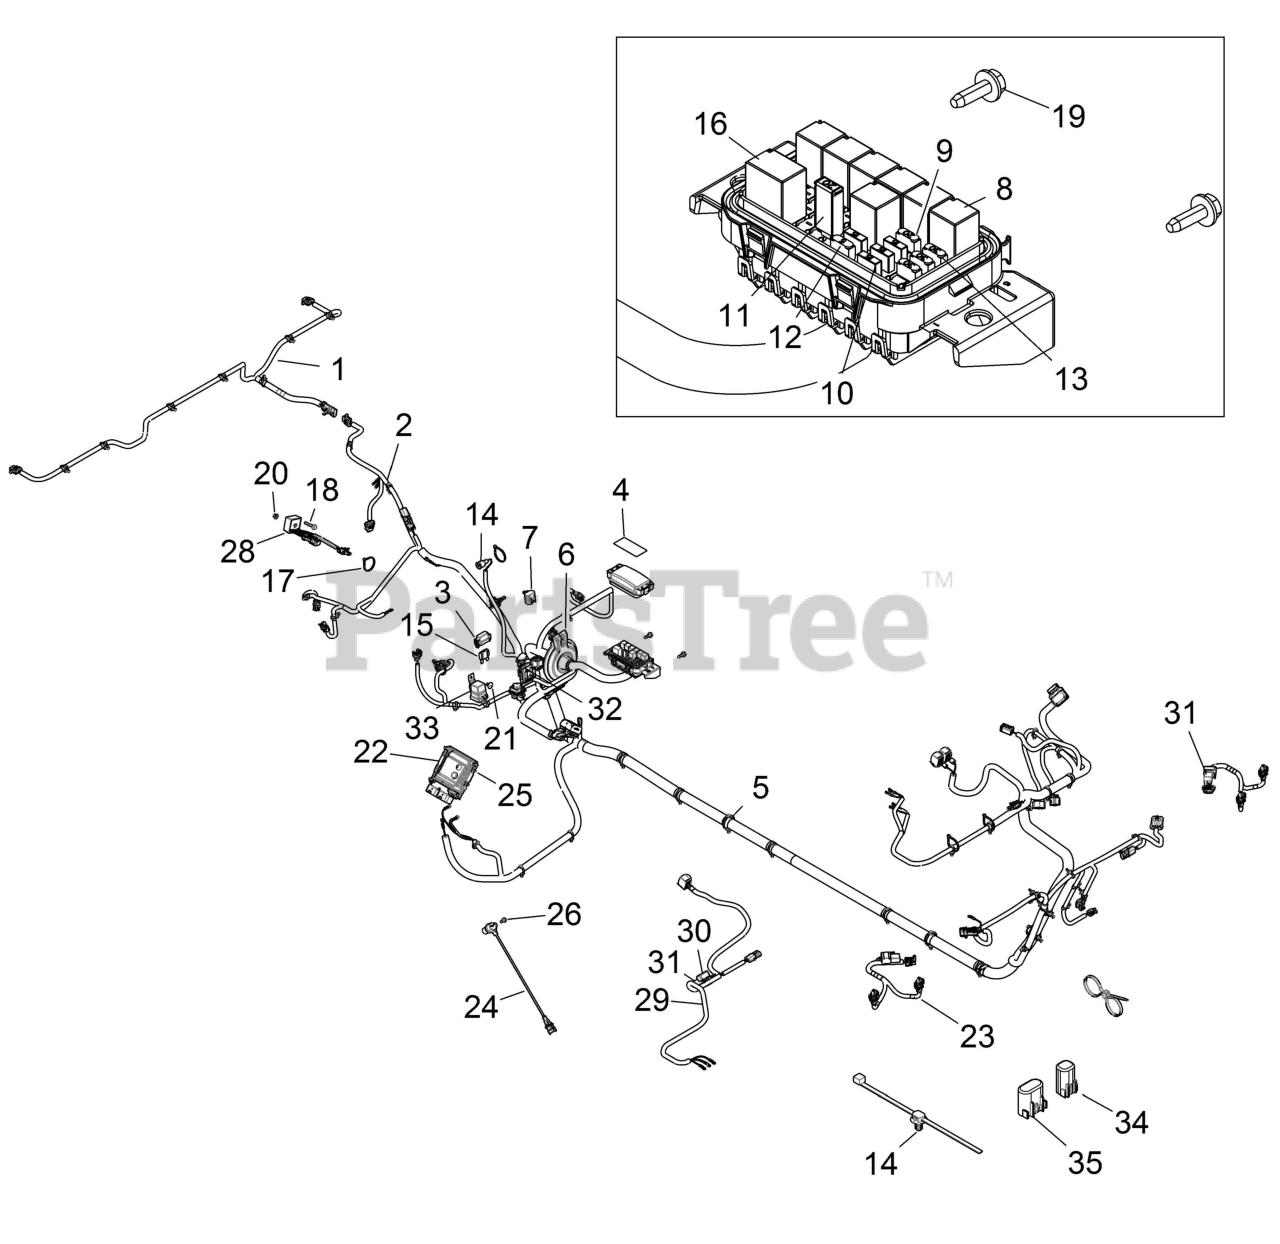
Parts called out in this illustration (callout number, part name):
1	HARNESS-BOX-ARIENS SPLY
2	KIT, FUSIBLE LINK, .8MM
2	KIT, FUSIBLE LINK, 1MM
2	KIT, FUSIBLE LINK, 2MM
2	HARNESS, CHASSIS
3	CLIP, X-MAS-TREE
4	DECAL, FUSE BLOCK
5	CLIP-ROUTING
6	GROMMET-CHASSIS HARNESS
7	COVER-DIAGNOSTIC,W/CLIP
8	RELAY-SPST,SERIES 303,SEALED
9	FUSE,PARK,20 AMP,(10)
10	FUSE, MINI BLADE, 15 AMP
11	BREAKER-CIRCUIT,20 AMP
12	FUSE-5A,MINI BLADE
13	FUSE,MAIN,30 AMP,(10)
14	BOOT, OIL PRESSURE SWITCH
15	TVS, 30VOLT
16	RELAY-SPDT,SERIES 301,SEALED
17	CABLE TIE (10)
18	BOLT-M6X1.0X35,HXFLG/SH-OLV D
19	SCR-M6X1.0X20,HXHD,FLG,TDFM,BL
20	NUT-M6X1.0,FLG-NYLOC-OLIVE D
21	CLIP, PLASTIC DART, NYLON
22	SERVICE ECU, ALL MY11 800 DOM
23	HARNESS-HEADLIGHT,ARIENS
24	SENSOR-CRANK POSITION
25	SCR-#10X1/2-HI/LO-PN-T25,TRX-M
28	RELAY, SOLID STATE,9A,LONG LD
29	HARNESS-BOX,LIFT
30	BREAKER-CIRCUIT,20 AMP,SEALED
31	RELAY-MICRO,SPST,35A,SEALED
32	FUSE-80 AMP
33	RELAY-GLOW PLUG
34	CONNECTOR-CAP,EPS SIGNAL
35	CONNECTOR-CAP,EPS POWER
